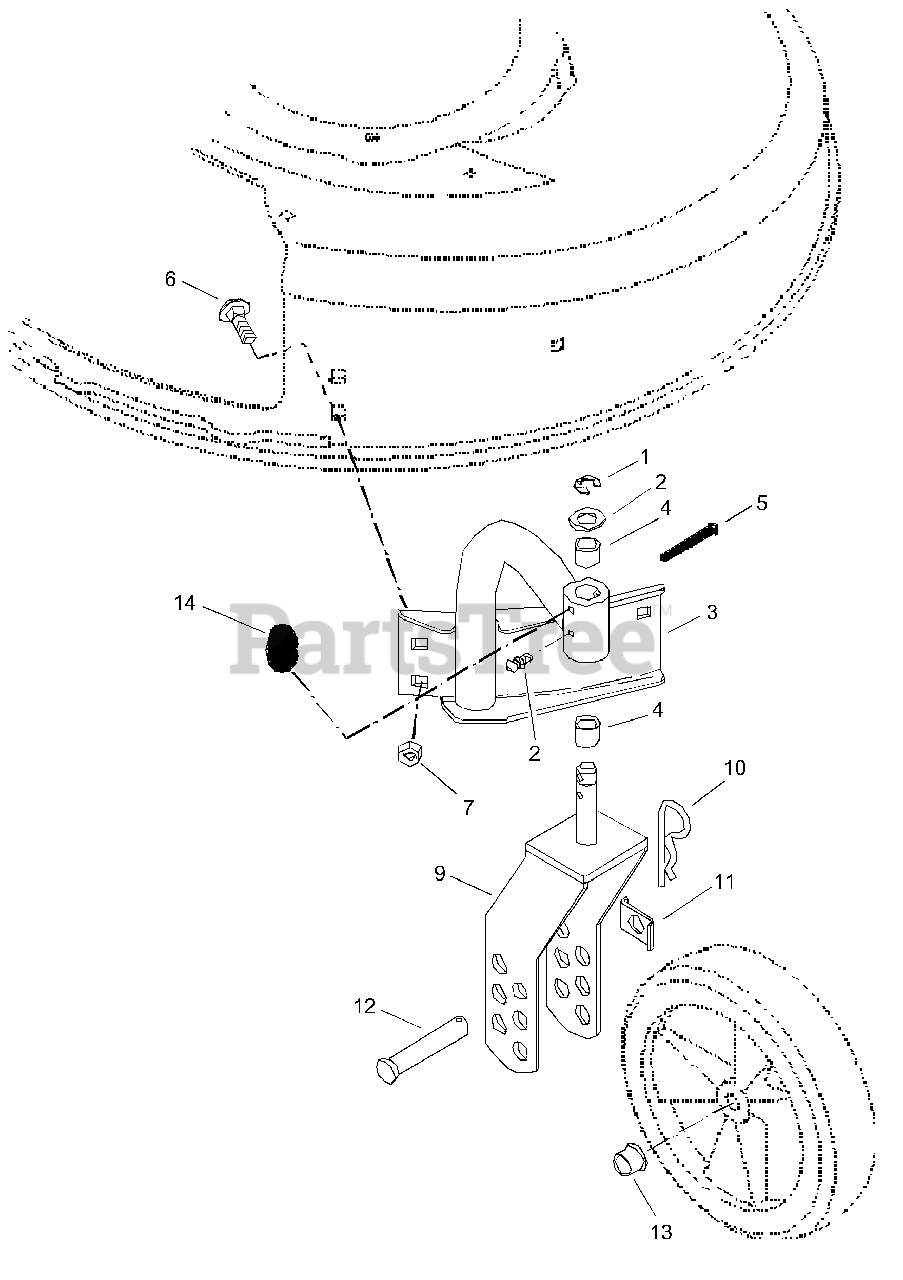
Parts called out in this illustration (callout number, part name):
1	RG-RTNG-EXT .625X.042
2	WSHR-FL-STL .630X1.005X.062 YZ
3	RIGHT MOUNT ARM WELDMENT
4	BSHG-SLV .625X.750X.500 BR
5	PIN-CLEV .25X1.75 YWZC
6	@BLT-RDHDSQNK .31-18X.50 G5YZ
7	@NUT-SPNLK-FLG .312-18 YWZC
8	FTG-LUBE .25-28X.256 YWZC
9	WHEEL YOKE WELDMENT
10	PIN-HAIR-INT .15X2.937 YWZC
11	AXLE TAB
12	PIN-CLEV .494X2.62 YWZC
13	BSHG-FLG .500X.625X.500X.750
14	KICKOUT RING YWZC
